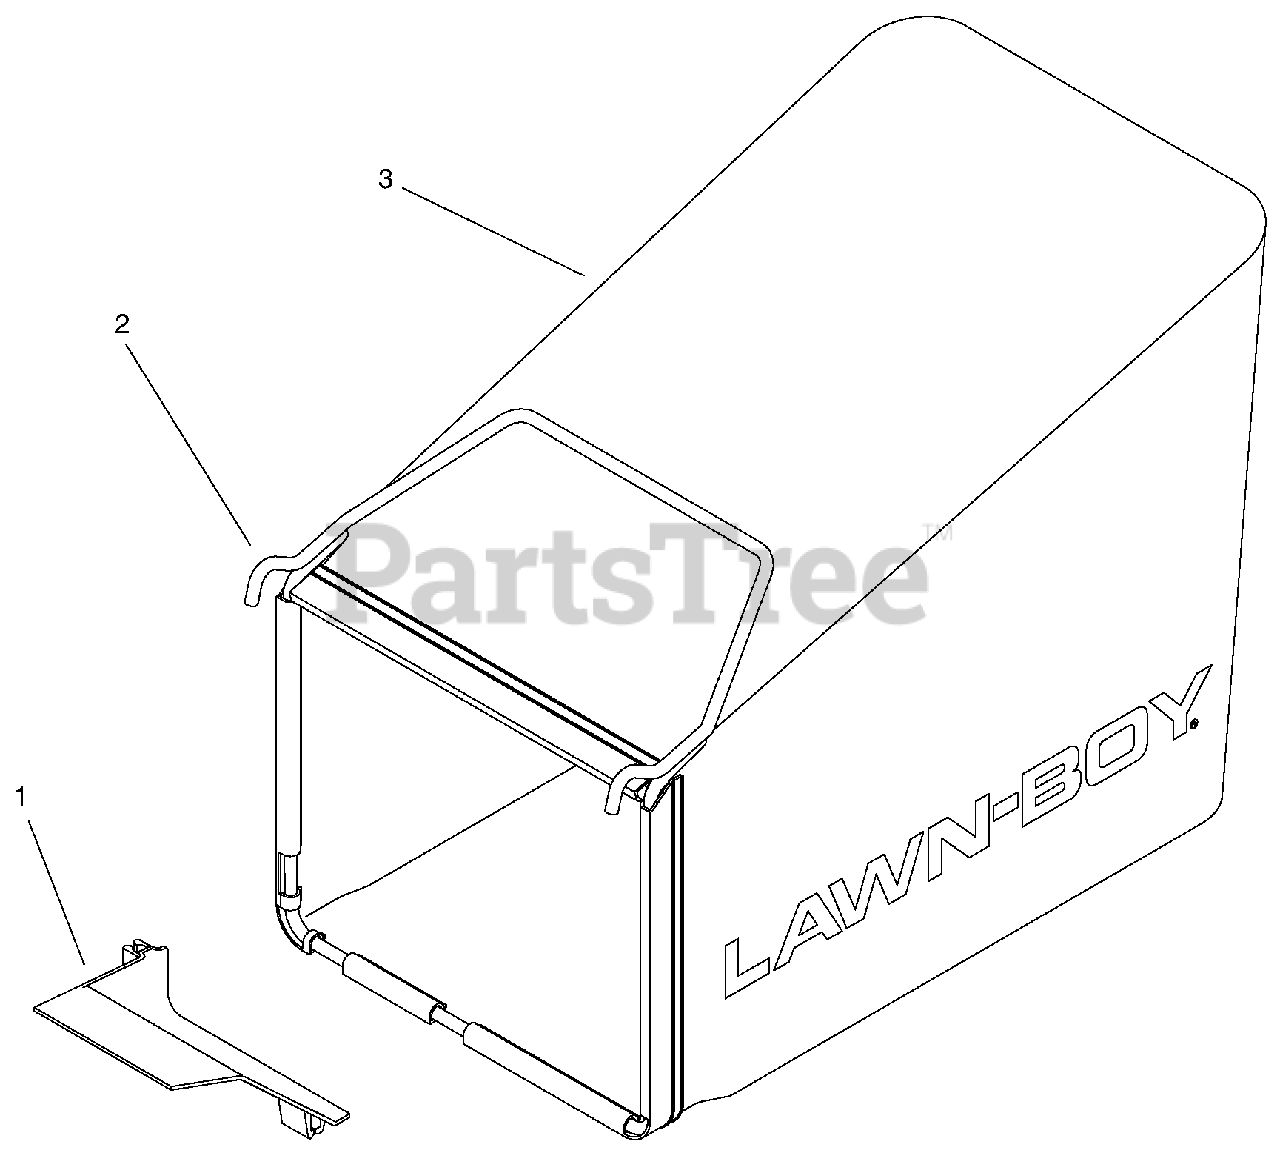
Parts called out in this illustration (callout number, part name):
1	BAG RAMP
2	Frame
3	GRASS BAG - 48CM LB
